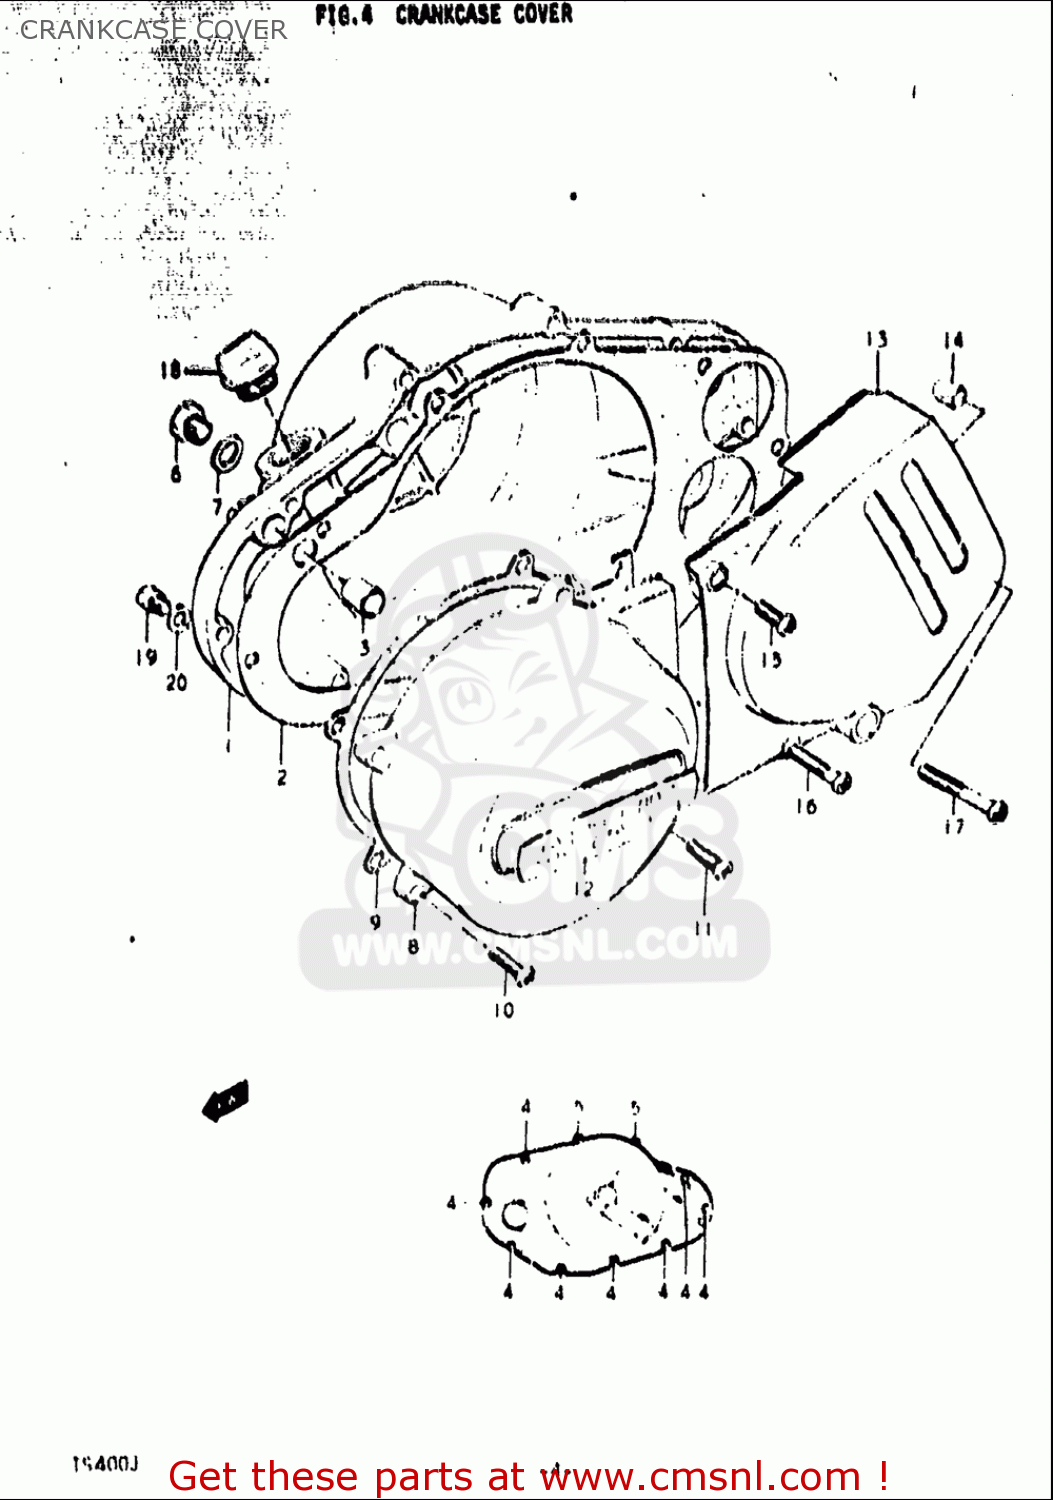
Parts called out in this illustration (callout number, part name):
3	PIN
4	SCREW
5	SCREW
6	PLUG
7	GASKET(10X14X3.6) (NAS)
10	SCREW
11	SCREW
14	PIN
15	SCREW
16	SCREW
17	SCREW
18	PLUG SET
19	SCREW(6X10)
20	GASKET(6.2X11X1) (NAS)
